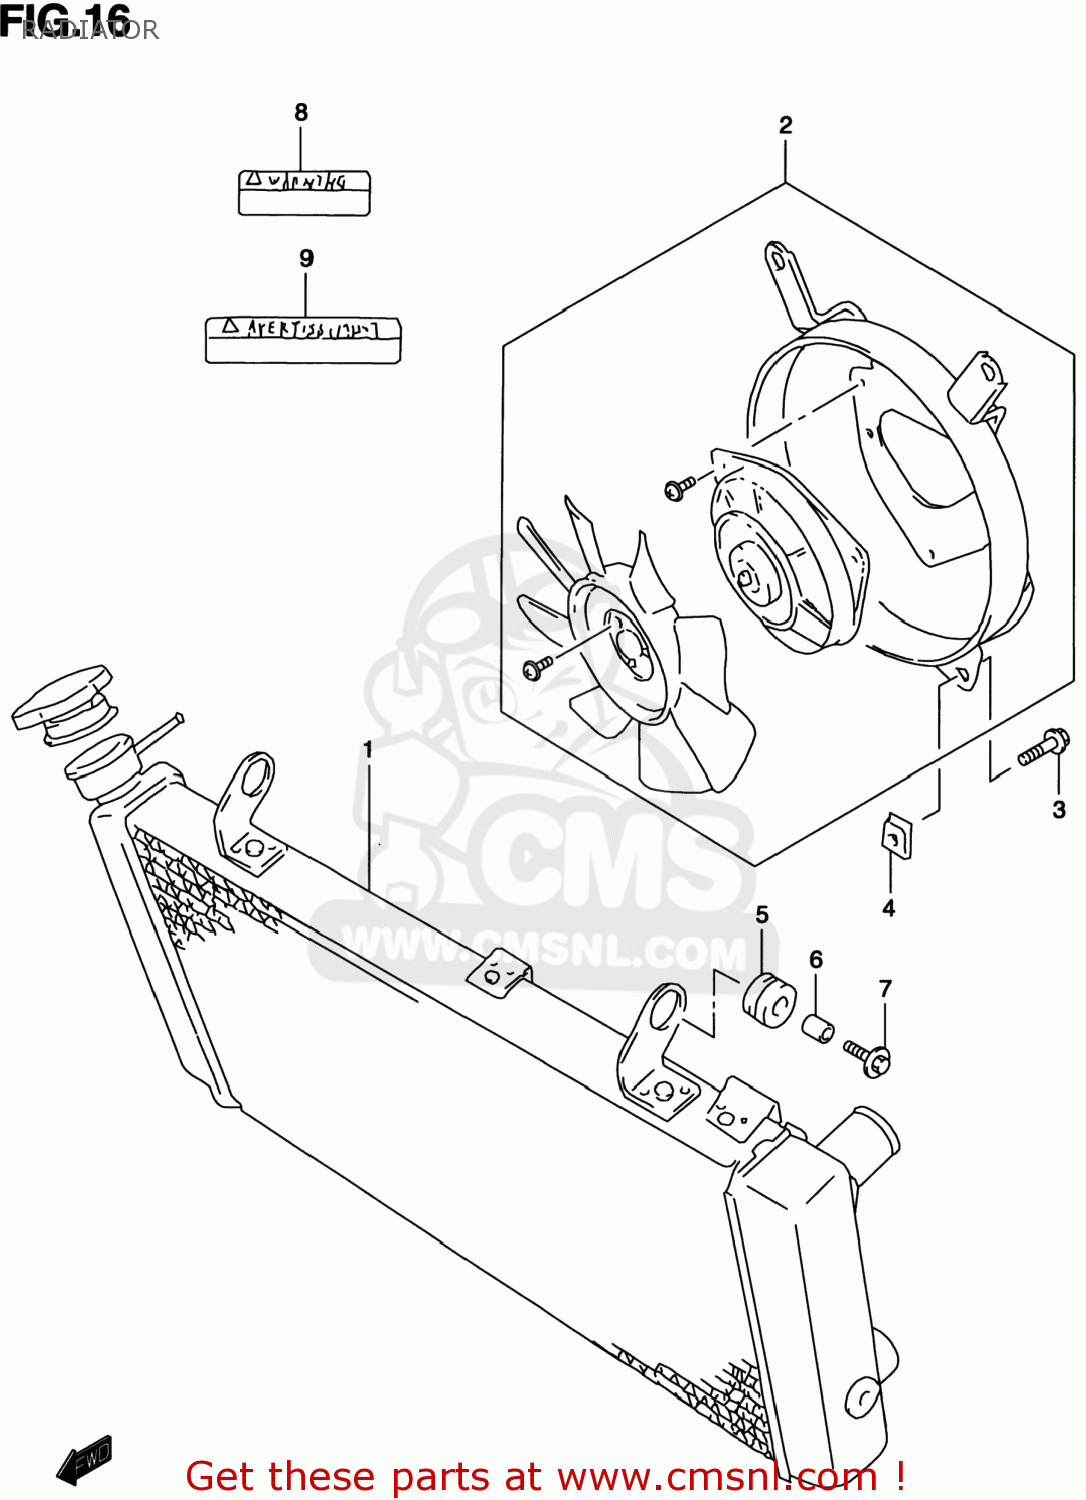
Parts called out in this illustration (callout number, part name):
1	RADIATOR ASSY,WATER
2	FAN ASSY,RADIATOR
3	BOLT
4	NUT
5	CUSHION
6	SPACER(6.5X10X12)
7	BOLT(6X25)
8	LABEL (COOLING FAN)
9	LABEL,COOLING FAN
